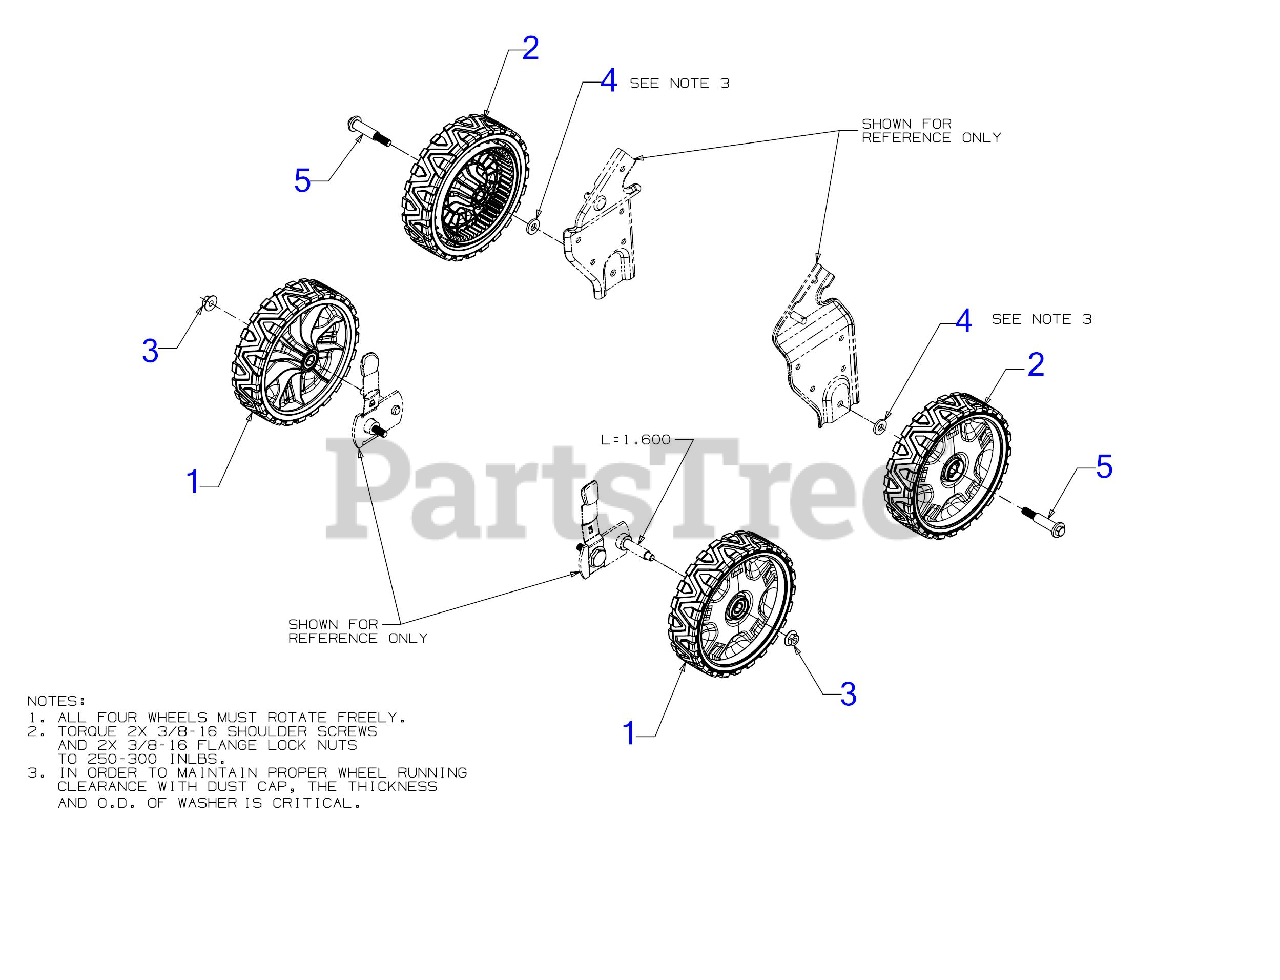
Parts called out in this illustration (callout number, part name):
1	WHEEL ASSEMBLY (8 x 2)
2	WHEEL ASSEMBLY (8 x 2)
3	FLANGE LOCK NUT
4	FLAT WASHER
5	SHOULDER SCREW .496X1.605 3/8-16
